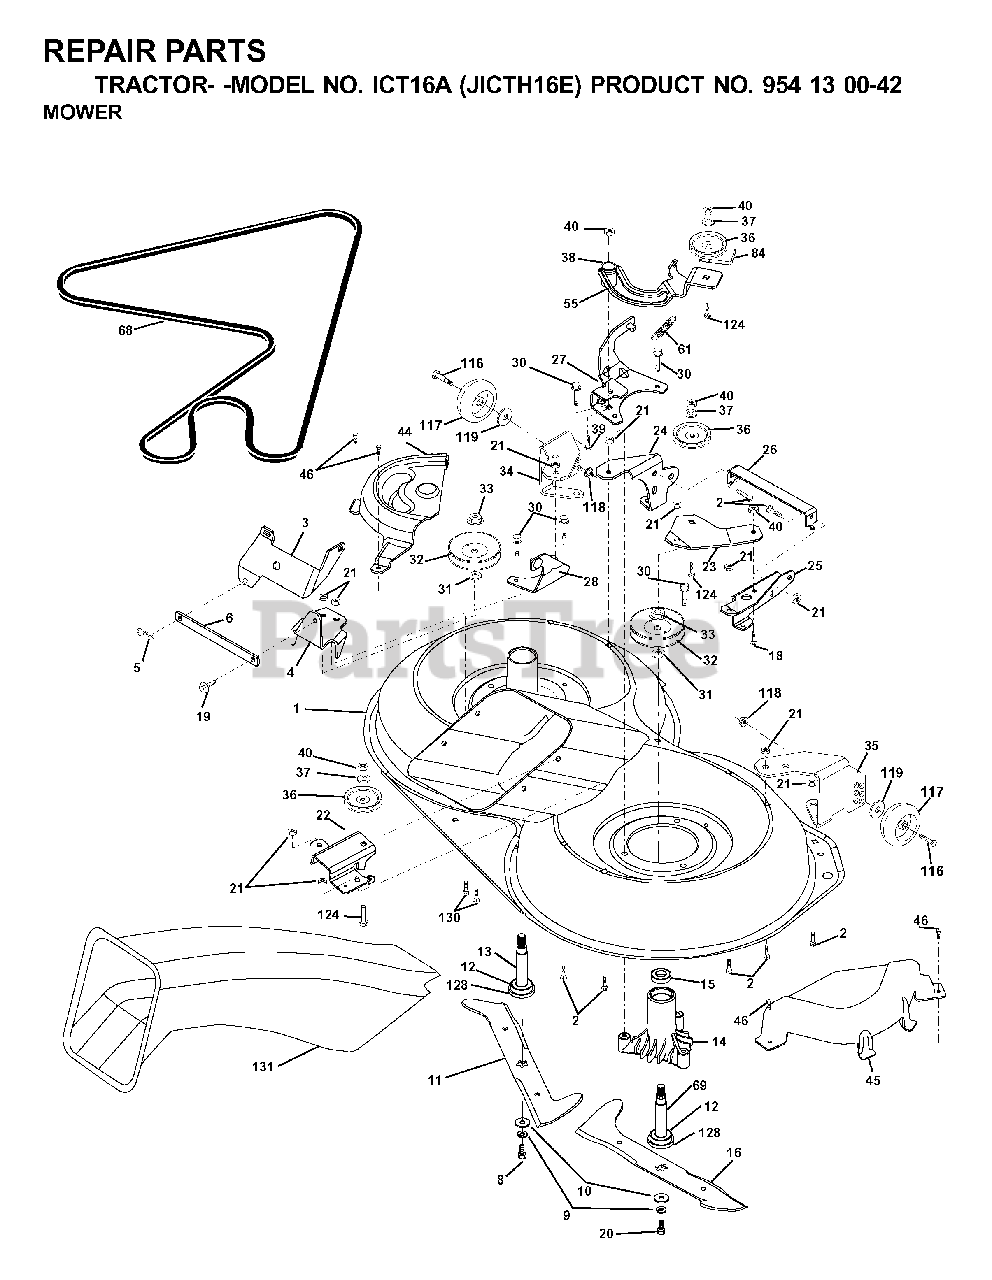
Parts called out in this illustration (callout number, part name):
2	BOLT
3	BRACKET
5	RETAINER-SPRNG RB
6	BAR SWAY
8	BLADE BOLT
9	LOCKWASHER
10	WASHER.BLADE
11	BLADE - LH (CTH150)
12	BEARING
13	SHAFT ASM VENT
14	HSG MANDREL
16	BLADE - RH (CTH150)
19	BOLT SHD 5/16-18
21	LOCKNUT
22	BRACKET
23	BRACKET
26	BRACE
27	BRACKET
30	SCREW THDROL ROLLING WASHER HD
31	WASHER
32	PULLEY/MANDREL
33	NUT
34	BRACKET
36	PULLEY.IDLER.4.25
40	LOCKNUT
45	MANDREL COVER RH
46	SCREW.1/4-20X5/8
55	ARM IDLER
61	SPRING.TENSION.BELT
68	HEX-BELT 107 MOWER
69	SHAFT.ASM.W/LWR.BRG.RH.THREAD
84	KEEPER, BELT IDLER
116	BOLT, SHOULDER
117	WHEEL GAGE DONUT
118	LOCKNUT
119	WASHER
124	BOLT.3/8-16X1.50
128	WASHER FELT
131	CHUTE BAGGER
